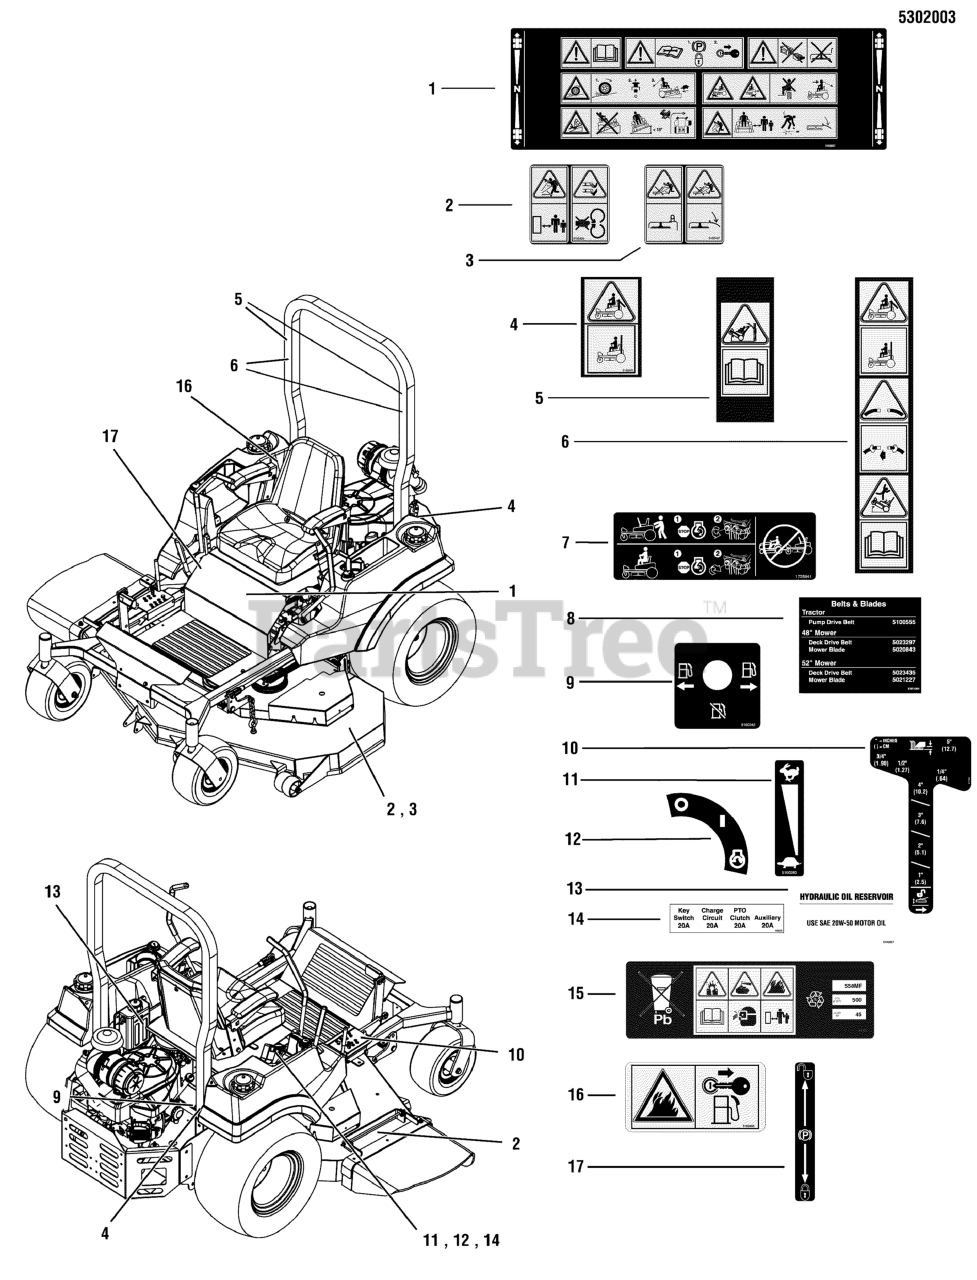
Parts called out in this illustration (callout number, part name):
1	DECAL, MAIN SAFETY, ANSI CE
2	DECAL, DANGER, MOWER DECK, ANSI EXP
3	DECAL, DANGER DISCHARGE ANSI EXPORT
4	DECAL, WARNING, ROLL BAR, CE
5	DECAL, SAFETY, CE ROPS, OBS
6	DECAL, SAFETY, CE ROPS
7	DECAL, CZT HYRDO RELEASE
8	DECAL, BELT & BLADE, S150XiCD DECK
9	DECAL, FUEL VALVE
10	DECAL-HEIGHT CITATION
11	DECAL, THROTTLE CONTROL
12	DECAL, IGNITION SWITCH
13	DECAL, HYDRAULIC OIL, SAE 20W50
14	DECAL, FUSE LOCATION
15	CE BATTERY DECAL, SMALL
16	DECAL, FIRE ANSI EXPORT
17	DECAL, PARKING BRAKE SYMBOLS
